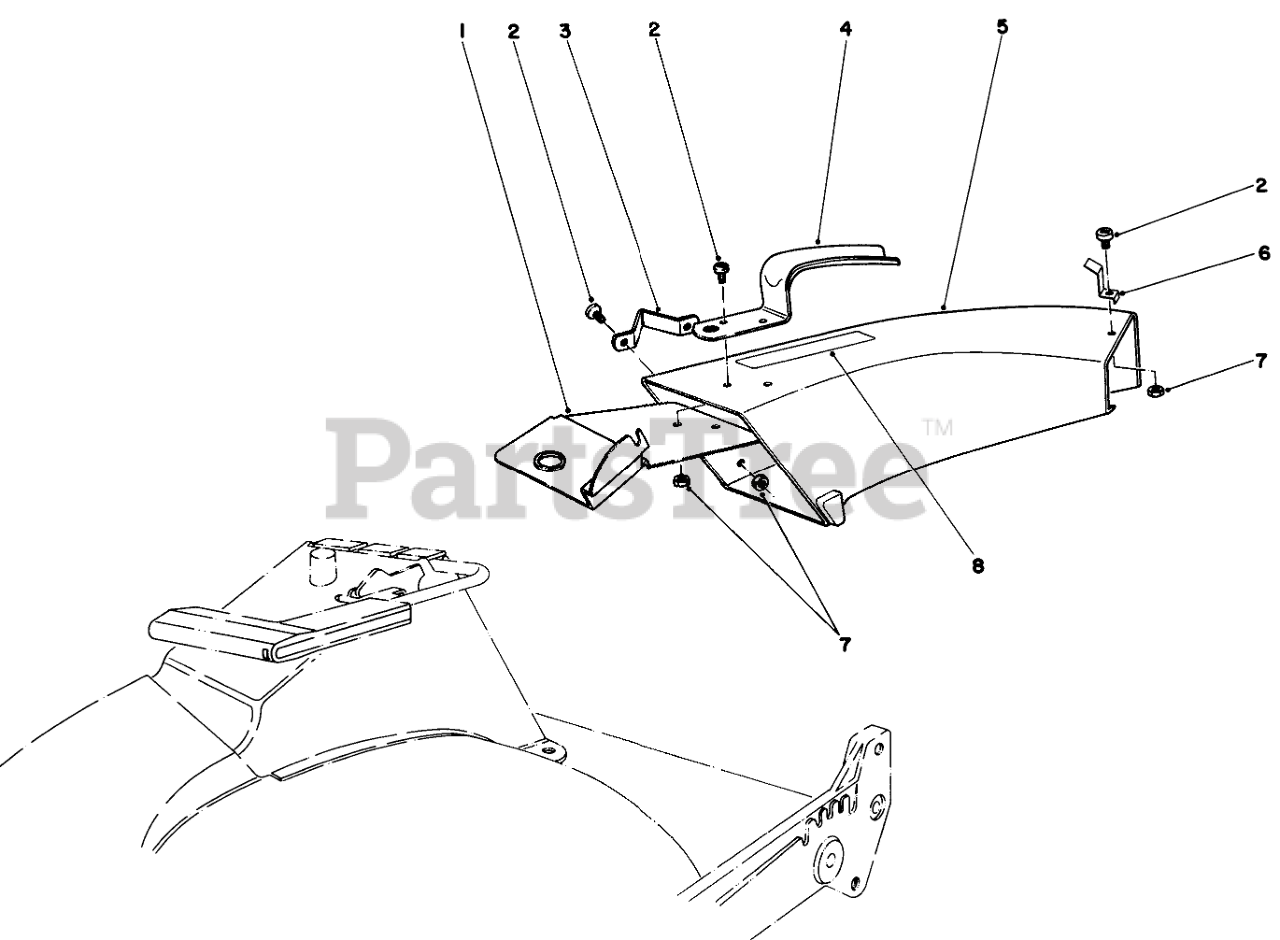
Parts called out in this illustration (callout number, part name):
1	Plate-Discharge Chut
2	10-24 X 5/8 PAN HD MS
3	SIDE BRACKET
4	CHUTE HANDLE
5	Chute-Discharge (Incl. Ref. #8)
7	NUT-LOCK, NI
8	DECAL CAUTION
